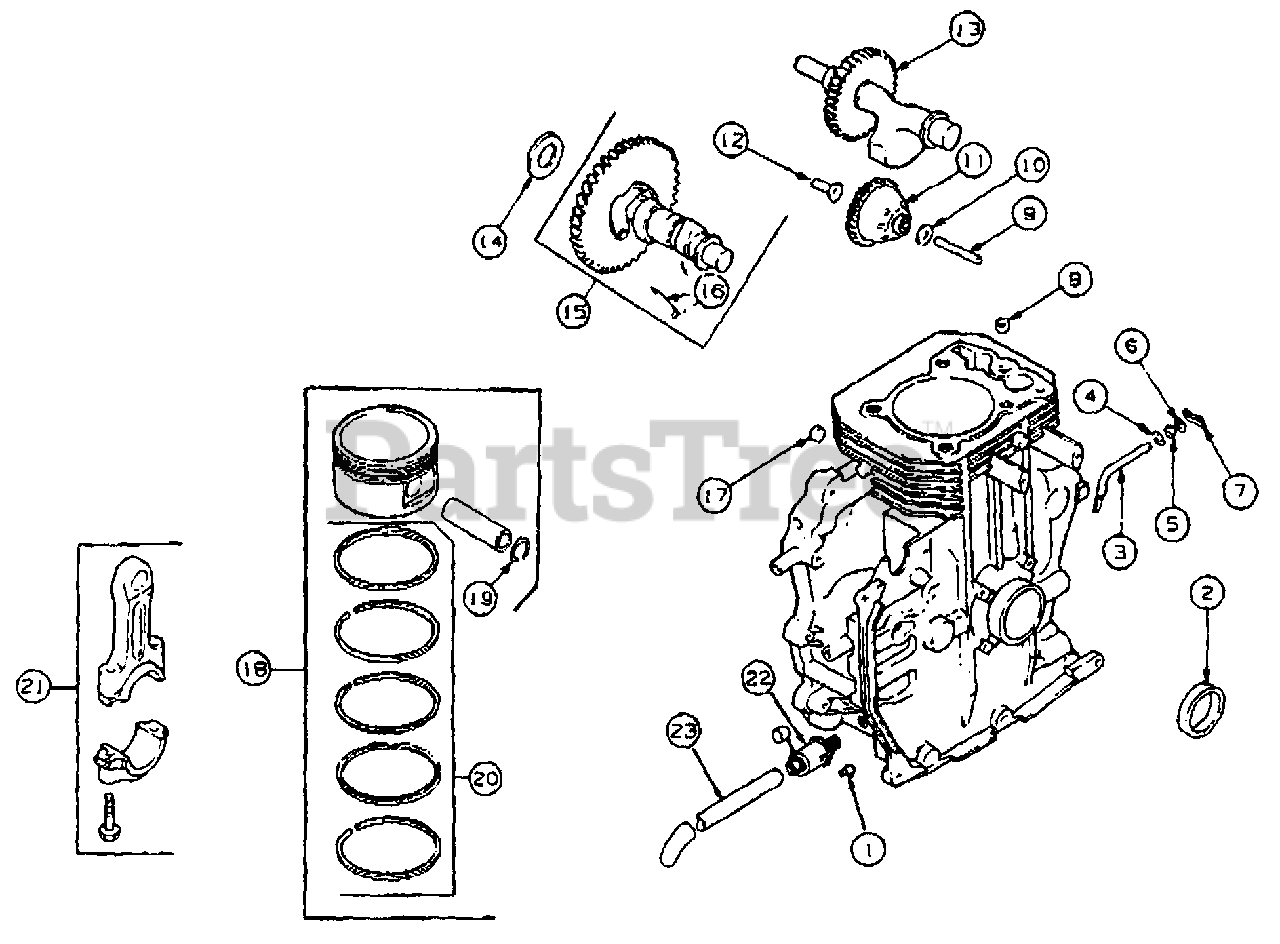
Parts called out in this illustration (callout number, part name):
1	Plug, Solid Sq Hd 3/8 NPTF
2	Seal, Crankshaft
3	Kit, Gov Cross Shaft
4	Washer, Governor Shaft
5	Seal, Governor Cross Shaft
6	Washer, Plain, 1/4
7	Pin, Governor Hitch
8	Dowel, Locating
9	Shaft, Governor Gear
10	Washer, Governor Gear Thrust
11	Gear, Governor Assy
12	Pin, Governor Regulating
13	Shaft, Balance
14	Shim, Camshaft, .0280
15	Camshaft Assy
16	Spring, Actuating
17	Plug, Cup
18	Piston w/Ring Set, Std
19	Retainer, Piston Pin
20	Ring Set, Std
21	Rod, Connecting, Std
22	Drain, Oil
23	Hose, Oil Drain
